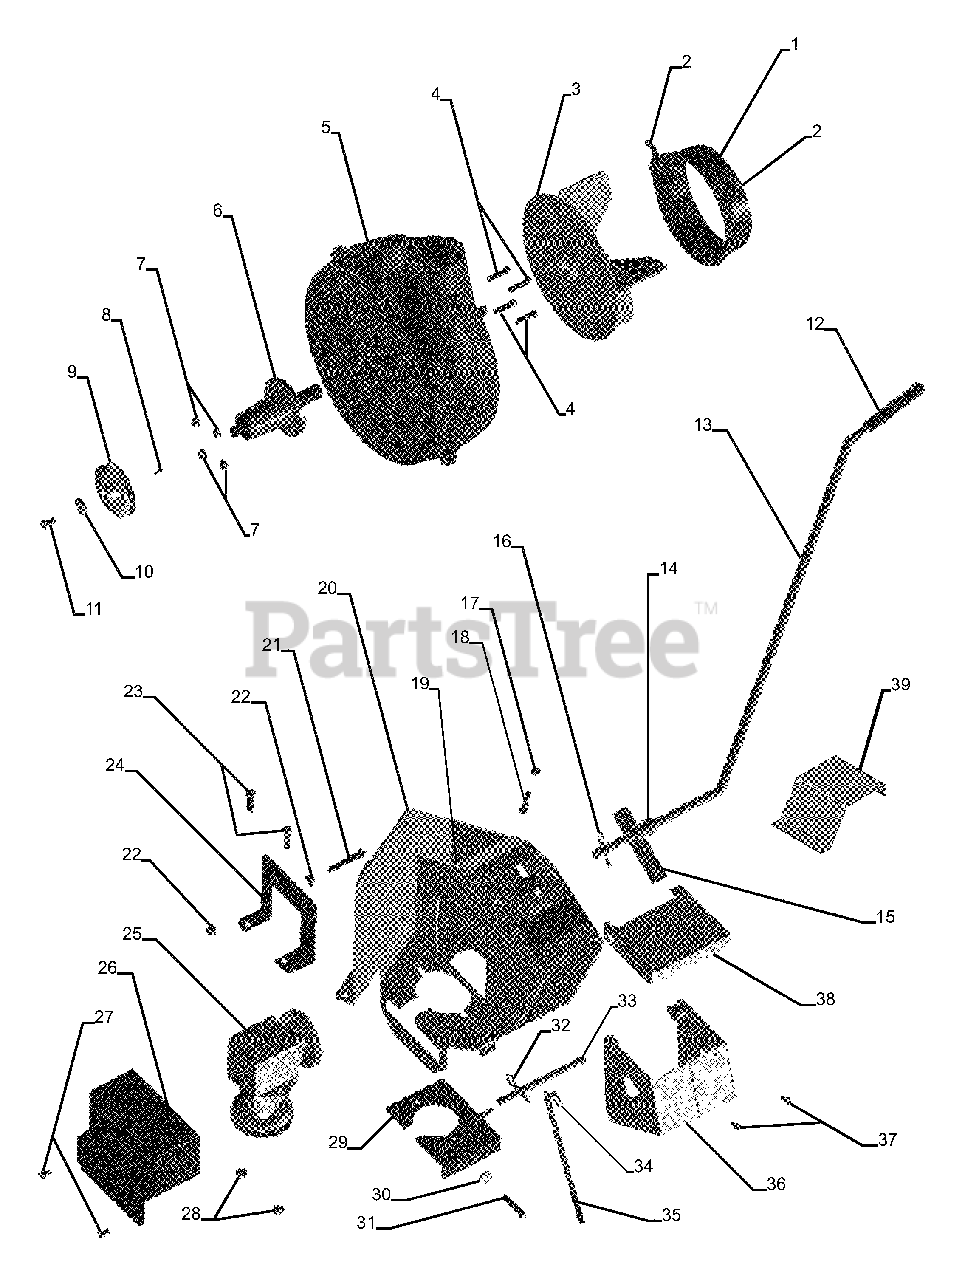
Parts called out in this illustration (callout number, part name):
1	Blower Cone 8"
2	5/16"-18 x 2" HHCS
3	4 Blade Impeller Assembly
4	3/8"-16 x 1-1/2" HHCS
5	Blower Housing Assembly
6	PTO Shaft Assembly
7	3/8"-16 Flange Nut
8	3/16" x 3/4" Key-way
9	Blower Pulley
11	3/8"-16 x 3/4" HHCS
12	5/8" Black Handle Grip
13	PTO Handle
14	3/8"-16 Set Screw
15	Cam Bracket Assembly
16	1/8" x 2-3/8" Hair Pin Clip
17	5/16"-18 Nyloc Nut
18	5/16"-18 x 2" HHCS
19	Safety Interlock Harness
20	PTO Arm Assembly
21	3/8"-16 x 2-1/2" HHCS
22	3/8"-16 Flange Nut
23	3/8"-16 x 1-1/2" HHCS
24	Belt Guide Bracket
25	Gear Box Assembly
26	Pulley Guard
27	1/4"-20 x 1/2" HHSTS
28	3/8"-16 Flange Nut
29	Belt Tension Bracket Assembly
30	3/8" Flat Washer
31	3/8"-16 x 2" HHCS
32	1/8" x 2-3/8" Hair Pin Clip
33	Blower Pivot Rod
34	3/32" x 2" Hair Pin Clip
35	Belt Tension Rod 3/8"-16
36	Blower Mount Bracket Assembly
37	1/4"-20 x 1/2" HHSTS
38	Blower Belt Guard
39	Skid Plate
